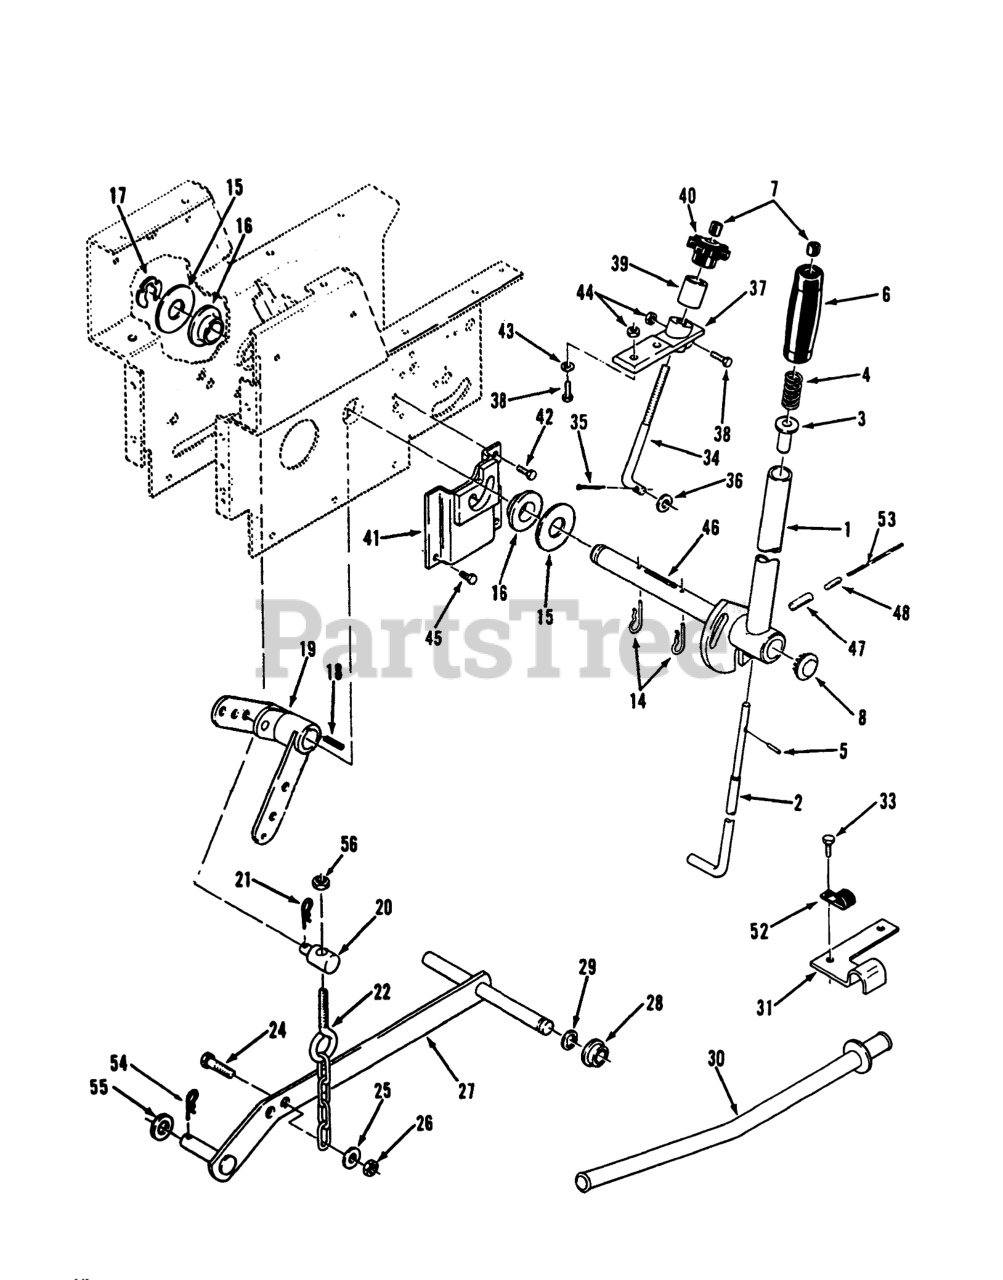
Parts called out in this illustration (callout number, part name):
1	Lever-Lift (Includes Items 46, 47, & 48)
2	ROD-LATCH LIFT
3	RETAINER-SPRING
4	SPRING-COMPRESSION
5	PIN-SPIROL
6	HANDGRIP
7	CAP-ROD, PLUNGER
8	PLUG
14	Pin-Cotter
15	WASHER-FLAT
16	BEARING-FLANGE
17	Retainer
18	KEY-SQUARE
19	LIFT LEVER ASM
20	TRUNNION-LIFT
21	Hairpin
22	CHAIN-LIFT
24	SCREW-HH
25	WASHER-PLAIN
26	NUT-LOCK, NI
27	Bar-Lift
28	BUSHING
29	E Ring
30	TUBE ASSY COMPLET R
31	CLAMP-CONDUIT R
33	SCREW-HH, LOCK
34	ROD-HEIGHT CONTROL
35	PIN-COTTER
36	WASHER-FLAT
37	Casting
38	SCREW-HH
39	Sleeve
40	KNOB-LIFT CONTROL
41	Latch Bracket
42	SCREW
43	WASHER-PLAIN
44	NUT-LOCK, NI
45	Bolt
46	SHAFT-LIFT LEVER
47	PIN-SPRING
48	PIN-ROLL
52	CLIP
53	Lock Wire
54	Hairpin Cotter
55	WASHER-FLAT
56	NUT-LOCK, NI
